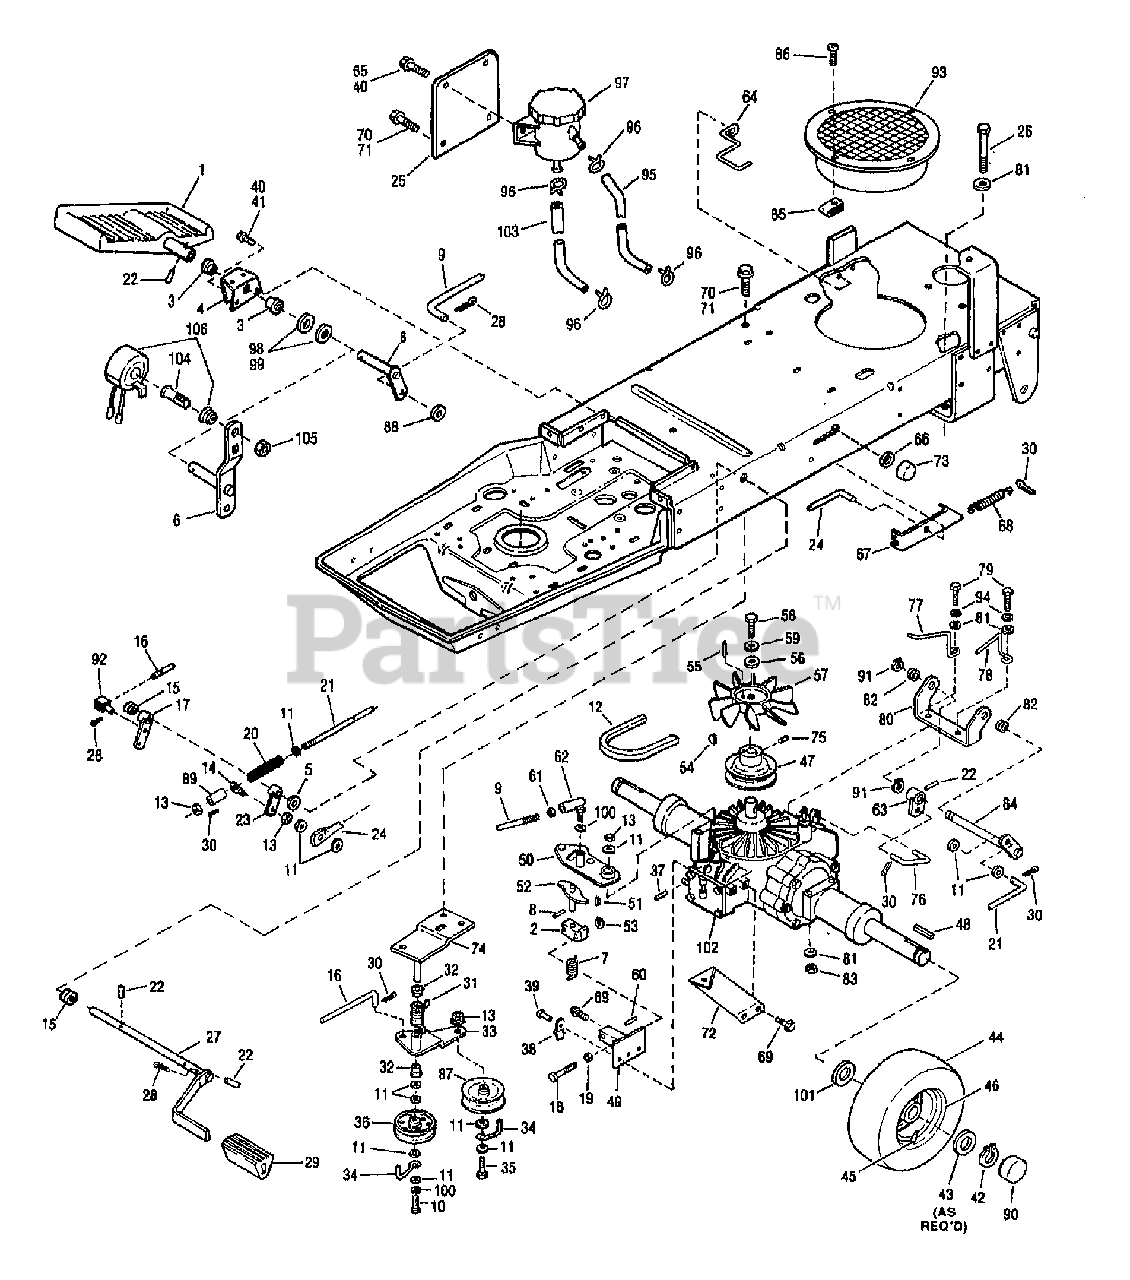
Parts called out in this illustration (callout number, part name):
2	BLOCK-PIVOT
3	BEARING-FLANGE
4	SUPT-HYD PEDAL
6	ASSM-CONTROL ARM
6	ASSM-CONT {3016HR,3016HRS}
7	SPRING-TORSION
8	PIN-ROLL .188X.75
9	ROD-SPEED CONTROL
13	NUT-LOCK 3/8-16
15	BUSHING-.68X.62X.15 FLNG
16	ROD-CLUTCH
17	ASSM-ARM
18	SCR-ADJUSTING
19	NUT-JAM
20	SPRING-COMP.
21	ROD-BRAKE
23	ASSM-ARM
24	ROD-BRAKE LOCK
27	ASSM-BRAKE PEDAL
29	FOOT REST
31	SPRING-TORSION
32	BELT-V
33	ASSM-IDLER ARM
34	GUIDE-BELT
38	LATCH
39	RIVET-POP
40	SCR-HH 1/4-20X.625
41	NUT-HF/LK 1/4-20 ZP
42	RING-RETAINING
43	WASHER-1.88X1.015X.06 ZP
45	STEM-VALVE
46	WHEEL-REAR
47	SHEAVE-HYDRO
49	ASSM-ADJUSTOR BLOCK
50	ASSM-SPEED CONT ARM
52	ASSM-PIVOT SHAFT
53	RING-RET.EXT .375 ID
56	WASHER-1.0X.281X.179 ZP
57	FAN-HYDRO TRANSMISSION
60	PIN-DOWEL .375 X 2.51
62	JOINT-BALL
63	ASSM-BRAKE ARM
64	GUIDE
65	NUT-HT LK 1/4-20
66	WASHER-FLAT
67	BRACKET-INTERLOCK
67	BRKT {3016HR,3016HRS}
68	SPRING
69	SCR-HFLK 5/16-18X.50 ZP
70	SCR-LOCK
71	NUT-HFLK 5/16-18 ZP
72	BRACE-TRANSAXLE
73	CAP-PUSH ON
74	ASSM-LEVER SUPP
75	SCR-SET 1/4-28X.38 HXSKT
76	BRAKE-LINK
77	GUIDE-BELT
78	GUIDE-BELT
80	SUPPORT-SHAFT
82	BEARING-FLANGED
83	NUT-TOP/LK 5/16-18 ZP
84	ASSM-JACKSHAFT
85	NUT-SPEED
87	PULLEY-IDLER
89	SPACER-.62X.406X.56 ZP
90	CAP-WHEEL
91	RING-RETAINING
92	PIVOT
93	SHROUD-FAN
95	HOSE-FUEL 18"
96	CLAMP-HOSE
97	ASSM-OIL RESERVOIR
98	WASHER-1.0X.64X.029
99	WASHER-1.0X.64X.09
101	SHIM-1.25X1.01X.06
102	KIT-CONVERSION W/HYDRO
104	SCR-SPECIAL
105	NUT-WHIZ LOCK {3016HR,3016HRS}
106	ASSM-MAGNET {3016HR,3016HRS}
